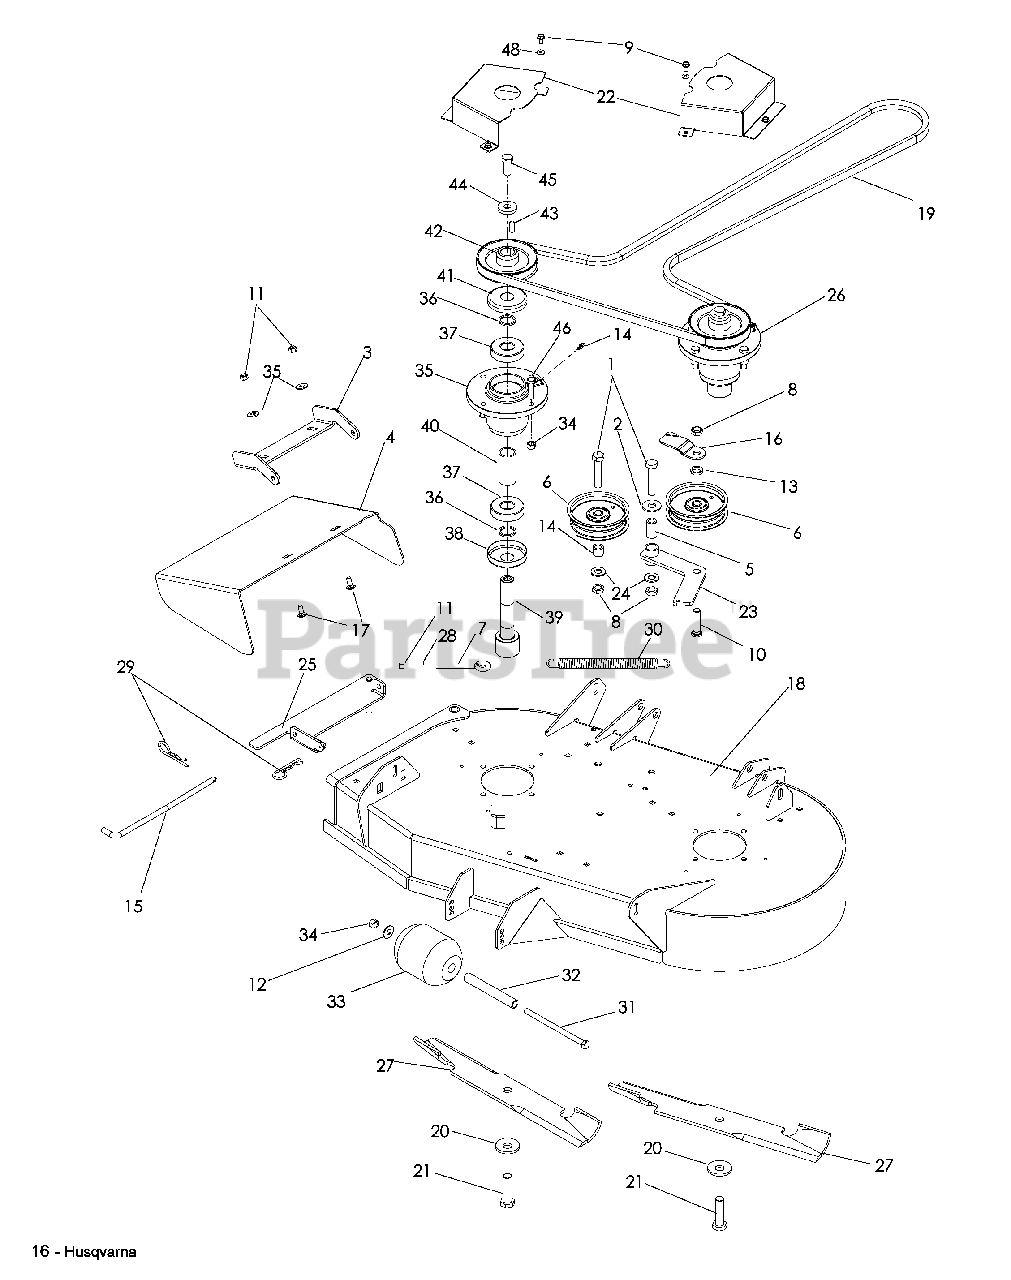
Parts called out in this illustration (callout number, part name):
1	HHB ½-13 x 2½
3	HINGE, DEFLECTOR
4	DEFLECTOR
5	BUSHING ½ ID x ¾ OD
6	IDLER PULLEY
7	EYEBOLT 5/16 x 3½
8	NUT ½-13 NYLOC
9	SCREW ¼-20 x 5/8, SELF TAP
10	STUD ½-13 x 2
11	NUT 5/16-18 NYLOC
12	WASHER 3/8
13	SPACER H.D. PULLEY
14	TUBE, .51 x.75 x .63
15	DEFLECTOR PIN
16	BELT GUARD
17	RHSNB 5/16-18 x ¾
18	DECK W/DECALS
20	BLADE WASHER
21	HHB 5/8-18 x 2¼ GR 8
22	PULLEY GUARD, 34
24	WASHER ½ NARROW
25	MOUNT, DEFLECTOR
26	SPINDLE ASSEMBLY
27	BLADE 34" HI-LIFT
28	WASHER 5/16
29	HAIR PIN COTTER
30	SPRING, DECK BELT
31	HHB 3/8-16 x 6
33	ROLLER, 3¾
34	NUT 3/8-16 NYLOC
36	HUB PULLEY SPACER
37	BEARING, 6305 2RS
38	TRASH GUARD
39	SHAFT, SPINDLE
41	TRASH GUARD
43	KEY ¼ x .88
44	WASHER, .525 x 1.375 x .25
45	HHB ½-20 x 1¼
46	HCS 3/8-16 x 1½
47	ZERK, GREASE
